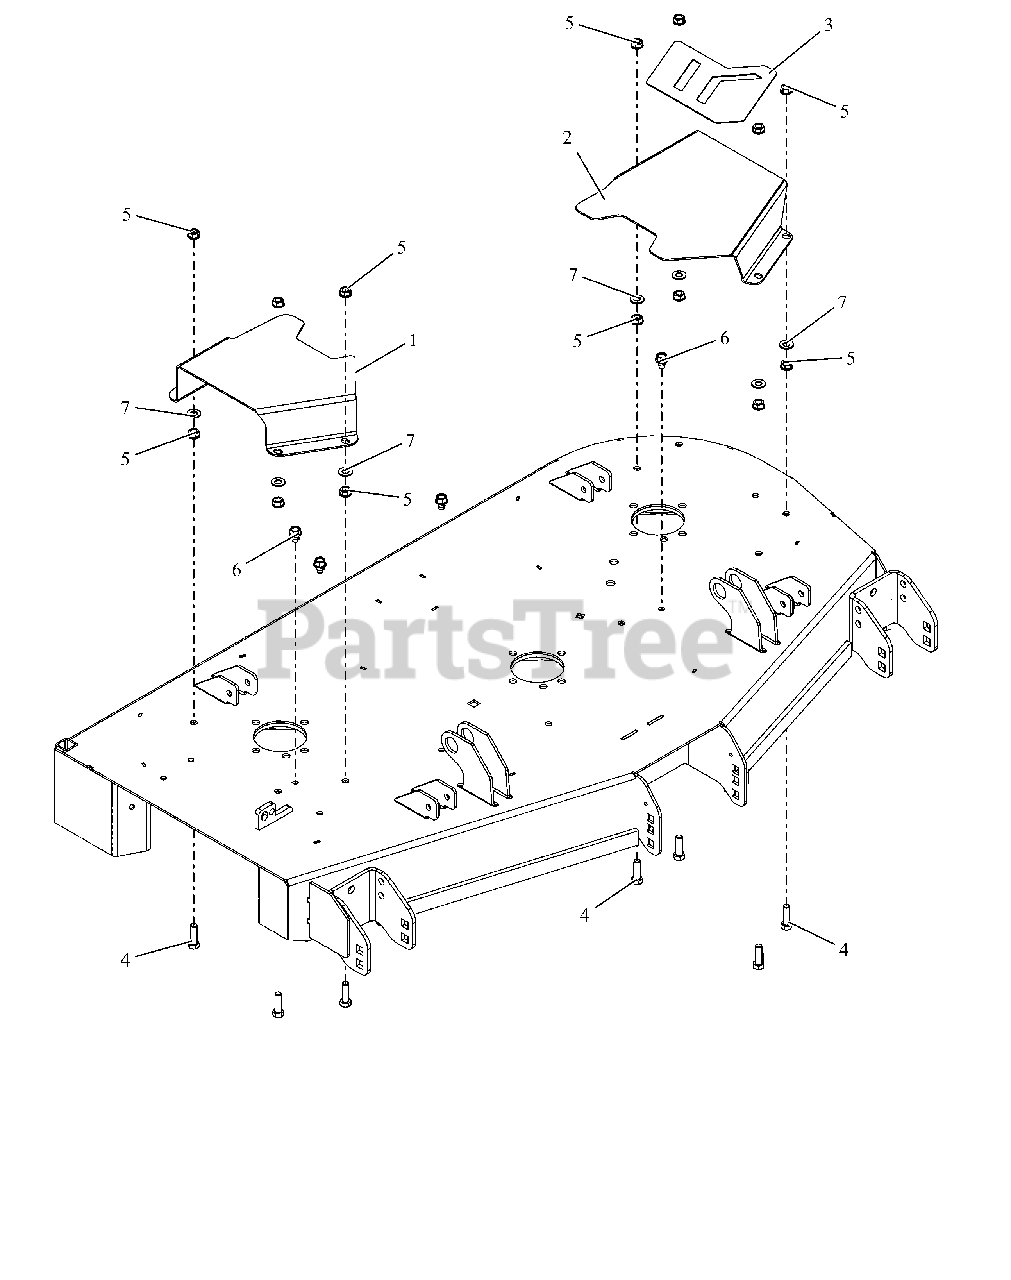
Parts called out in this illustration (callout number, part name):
1	COVER, BELT 48" RIGHT
2	COVER, BELT 48" LEFT
3	GRIP, TAPE 48 BELT COVER
4	BLT, HEX .38-16X1.25 G5 ZCC
5	NUT, SPNLK-FLG .38-16 G5 ZCC
6	SCR,TAP .375-16X.50 HWH TR ZCC
7	WSHR,FLT .406X.812X.065 ZCC
